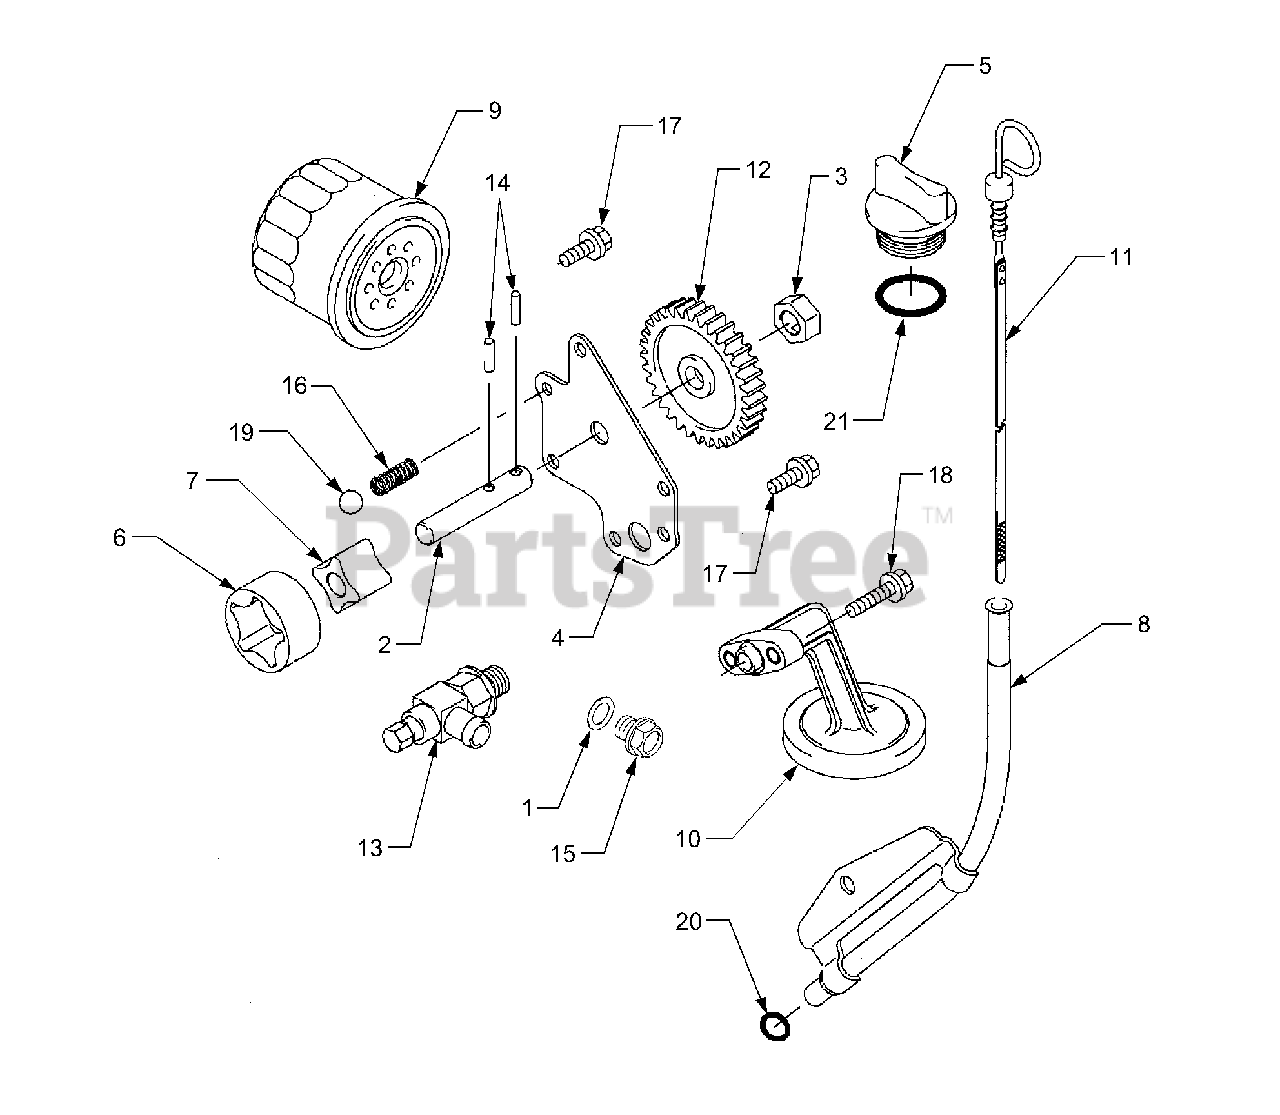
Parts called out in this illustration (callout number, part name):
1	Gasket, Drain Plug
2	Shaft, Oil Pump
3	Holder, Oil Pump
4	Cover, Oil Pump
5	Cap, Oil Filler
6	Rotor, Pump Outer
7	Rotor, Pump Inner
8	Pipe, Oil Gauge
9	Filter, Oil
10	Filter, Oil Suction
12	Gear, Spur, 33T
16	Spring
17	Bolt, Flanged
18	Bolt, Flanged
19	Ball, Steel
